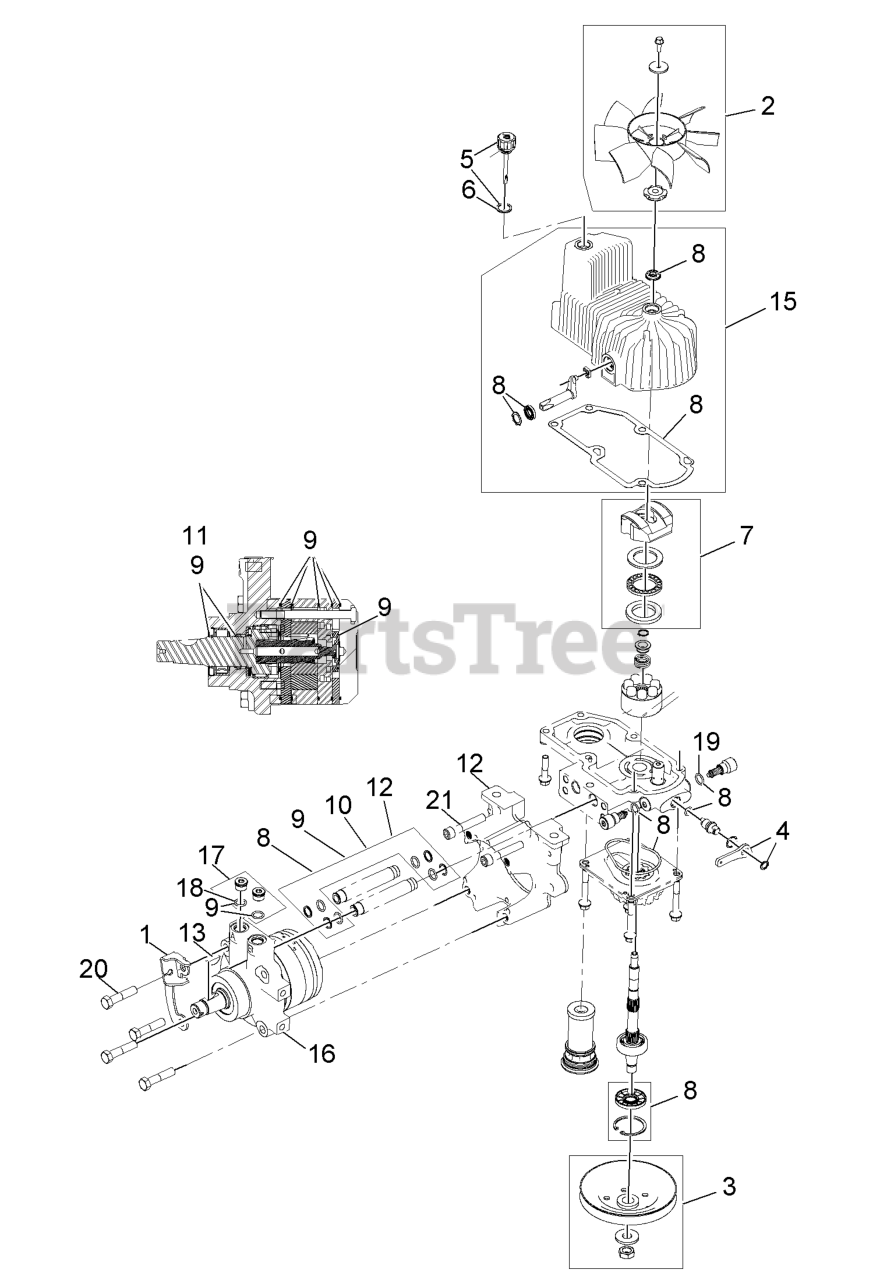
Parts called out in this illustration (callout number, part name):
1	BRACKET-ANCHOR, CABLE
2	FAN KIT
3	PULLEY KIT
4	HANDLE-BYPASS VALVE, HYDRO
5	DIPSTICK-HYDRO W/GASKET
6	GASKET-DIPSTICK, HYDRO
7	SWASH BLOCK KIT
8	PUMP SEAL KIT
9	MOTOR SEAL KIT
10	TUBE SEAL KIT
11	OUTPUT SHAFT SEAL KIT
12	NOSE CUP-UHT
13	KEY-WOODRUFF
15	HOUSING-HYDRO, LH
16	MOTOR-HYDRAULIC, LH 280CC
17	MAGNETIC PLUGS SERVICE KIT
19	O-RING-CHECK VALVE
20	SCREW HH
21	SCREW-HSH
